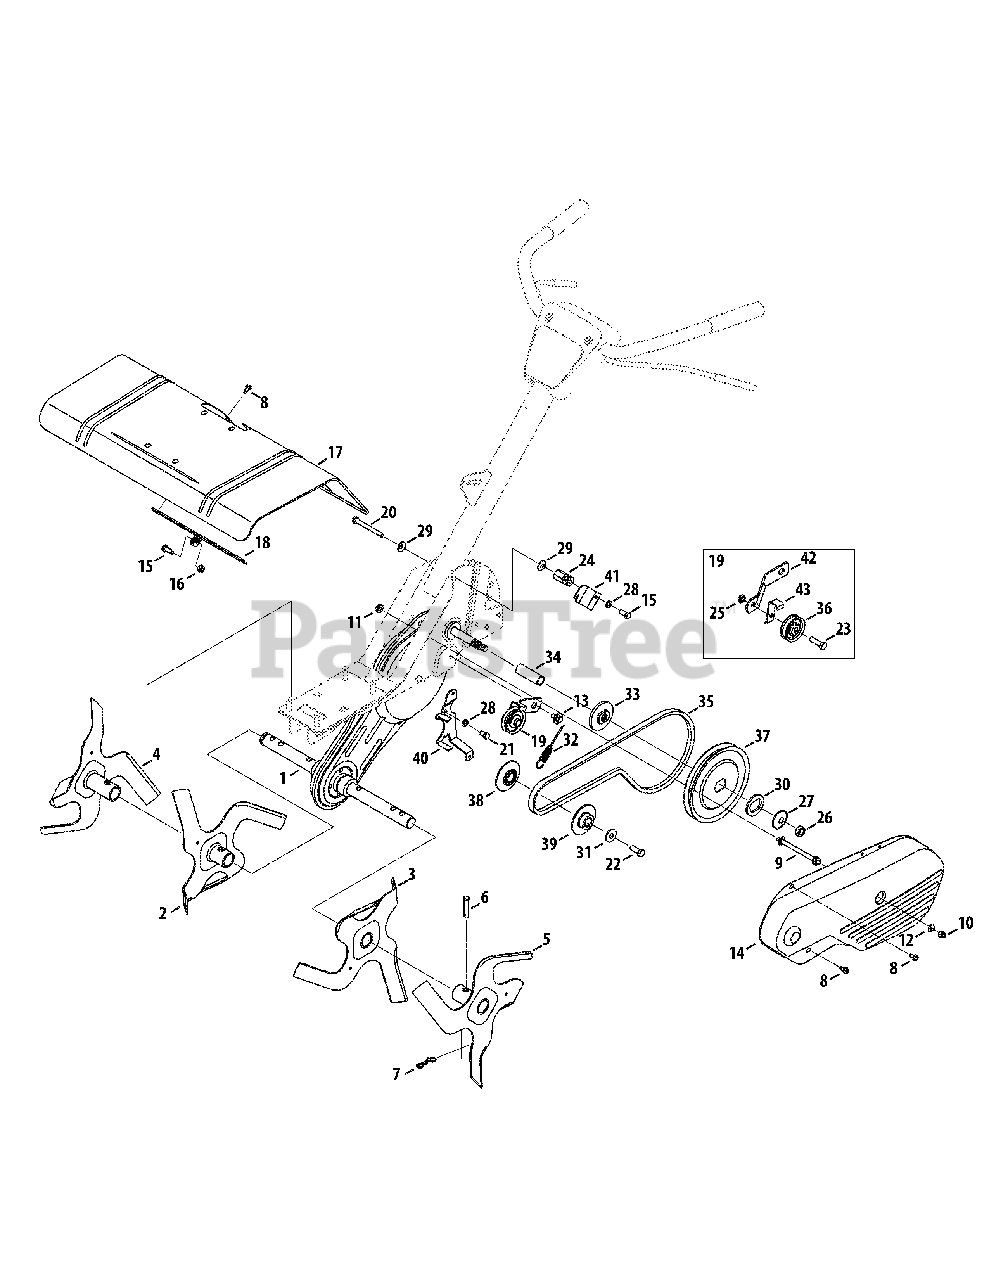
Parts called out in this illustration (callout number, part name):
1	Chain Case Assembly
2	Inner Tine Assembly, RH
3	Inner Tine Assembly, LH
4	Outer Tine Assembly, RH
5	Outer Tine Assembly, LH
6	Clevis Pin, .375 x 1.75
7	Bow Tie Cotter Pin
8	Screw, 1/4-20 x 0.500
9	Bolt, Belt Cover
10	Nut, 1/4-28, Lock
11	Nut, 5/16-18, Flange Lock
12	Flat Washer, .271 x .630 x .065
13	Shoulder Screw, .560 x .165 5/16-18
14	Belt Cover
15	Hex Head Screw, 5/16-18 x .75
16	Nut, 5/16-18, Flange Lock
17	Tine Shield
18	Bracket, Tine Shield
19	Idler Bracket Assembly
20	Hex Head Screw, 5/16-18 x 3.00
21	Hex Head Screw, 5/16-24 x .625
22	Hex Head Screw, 3/8-24 x 1.00
23	Hex Head Screw, 3/8-16 x 1.25
24	Hex Nut, 5/16-18
25	Jamlock Nut, 3/8-16
26	Nut, 1/2-20, Jam
27	Washer, .531 x 1.62 x .045
28	Lock Washer, 5/16
29	Bell Washer, .340 x .872 x .060
30	Flat Washer, 1.26 x 1.87 x .150
31	Bell Washer, .396 x 1.140 x .095
32	Forward Clutch Cable
33	Pulley Adaptor
34	Spacer, .64 ID x 2.4
35	Belt, 4L x 41.9 LG
36	Pulley 1.88 OD
37	Pulley 6.00 OD
38	Inner Engine Pulley
39	Outer Engine Pulley
40	Belt Keeper Bracket
41	Cable Guide Bracket
42	Idler Bracket
43	Belt Keeper
